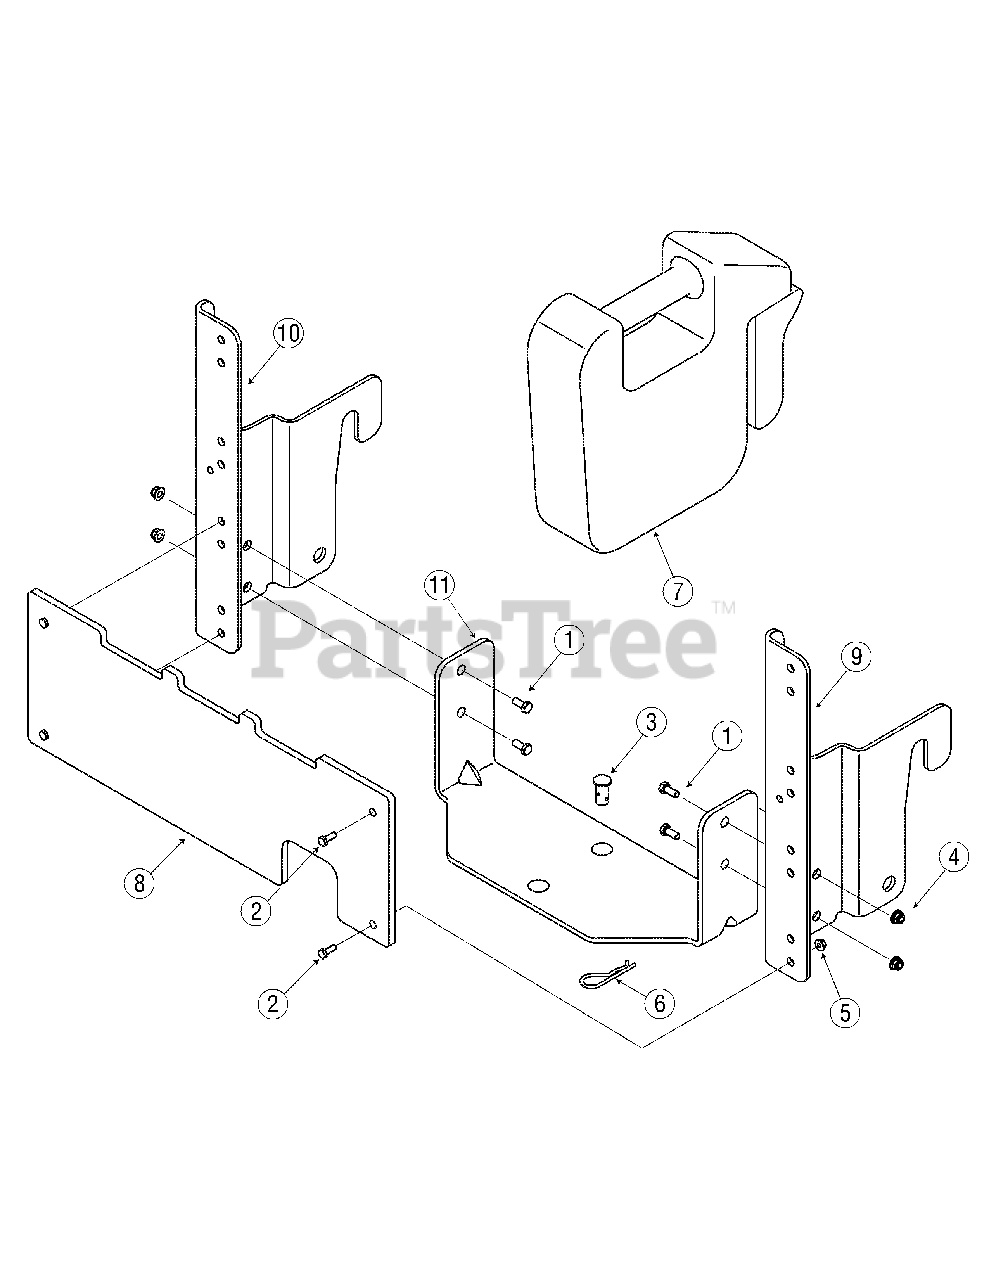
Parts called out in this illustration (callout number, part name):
1	Hex Head Screw, 5/16-18 x .75"
2	Hex Head Screw, 1/4-20 x .75
3	Clevis Pin, .62 Dia.
4	Flange Lock Nut, 5/16-18
5	Flange Lock Nut, 1/4-20
6	Internal Cotter Pin, .148 x 3.00
7	Suitcase Weight, 45 lbs.
8	Rear Weight Plate
9	Catcher Support Bracket, Right Hand
10	Catcher Support Bracket, Left Hand
11	Cross Support Bracket
